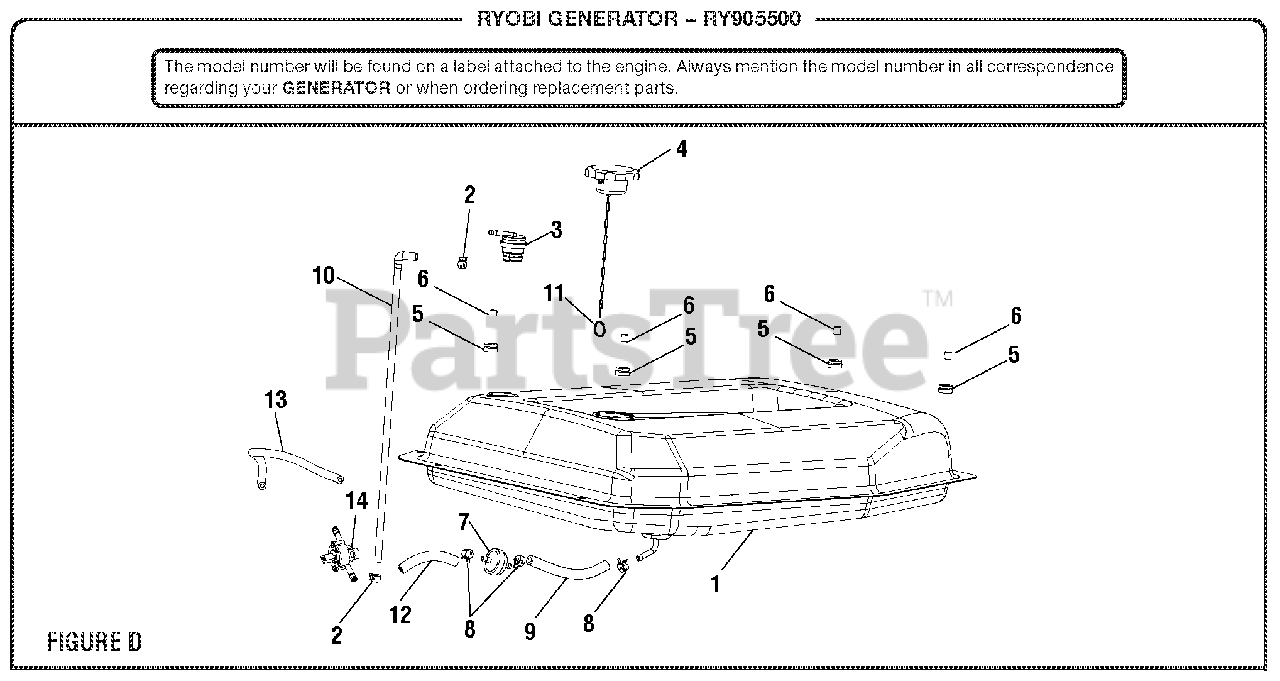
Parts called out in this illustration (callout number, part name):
1	Fuel Tank
2	Fuel Line Clamp (7/16 in.)
3	Vapor Vent
7	Fuel Filter Inline (1/4 in.)
8	Fuel Line Clamp (1/2 in.)
9	Fuel Hose (175 mm)
10	Vapor Hose
11	Ring Clip
12	Fuel Hose (85 mm)
13	Fuel Hose (330 mm)
14	Fuel Valve
